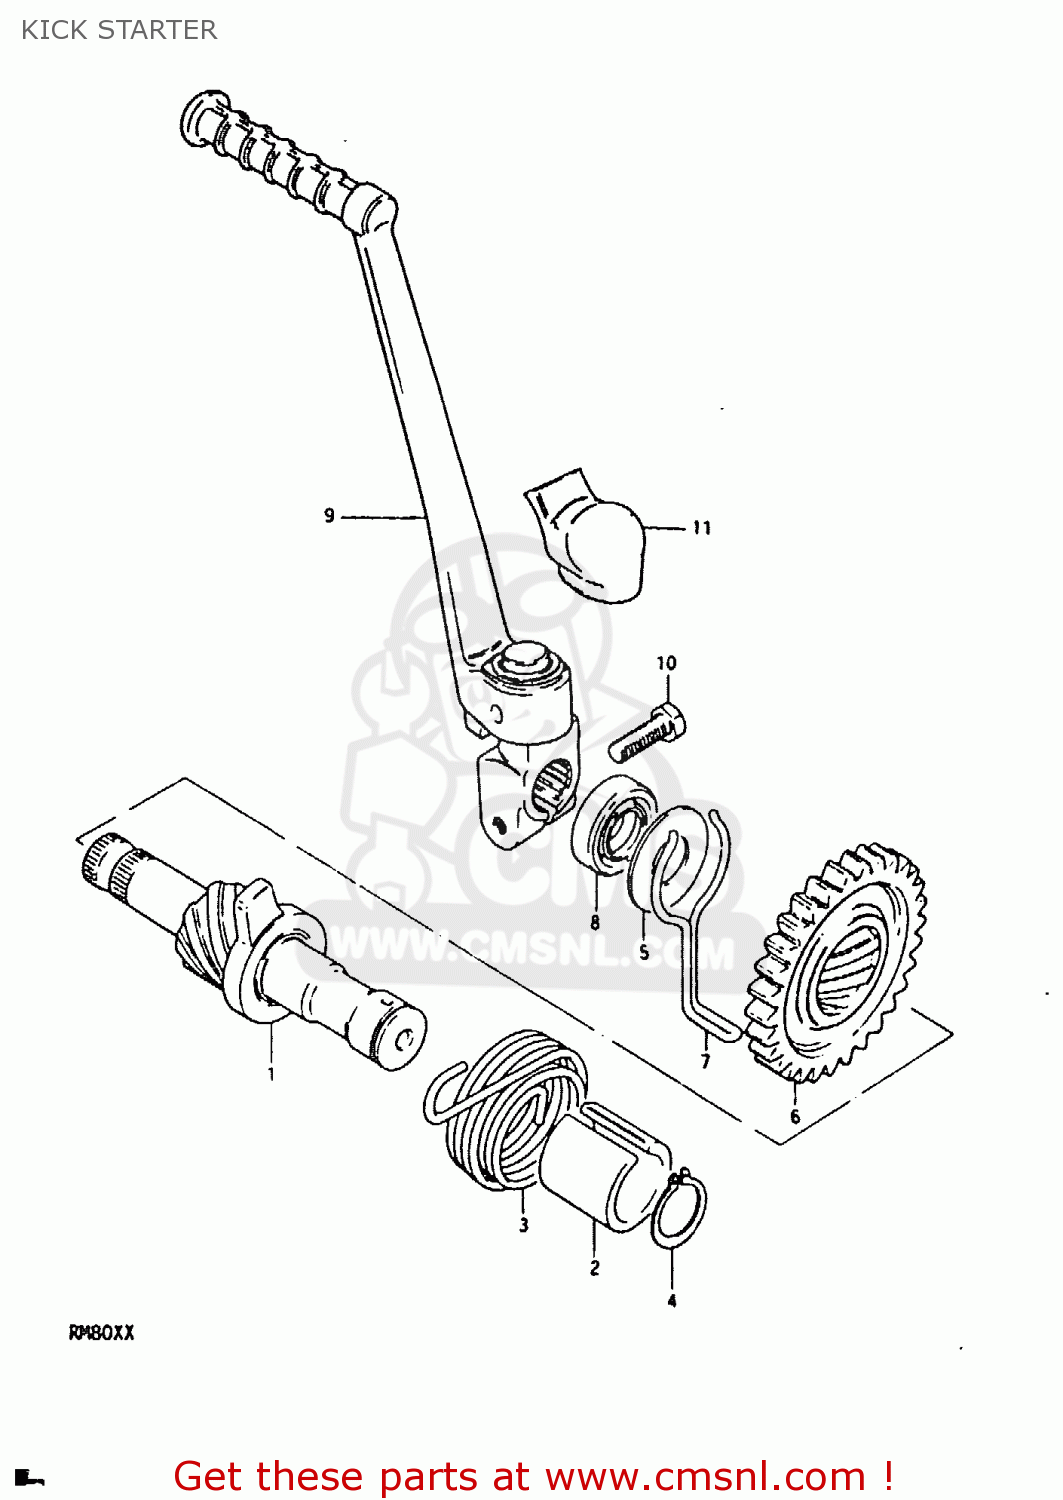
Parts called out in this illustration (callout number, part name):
1	SHAFT,KICK STARTER
2	CIRCLIP,16MM
3	GUIDE,KICK STARTER SFT SPRING
4	SPRING
5	WASHER
6	GEAR,KICK STARTER DRIVE(NT:30)
7	RETAINER,SNAP
8	SEAL,OIL(14X24X6)
9	LEVER ASSY,KICK STARTER
10	BOLT
11	COVER,KICK STARTER PEDAL
